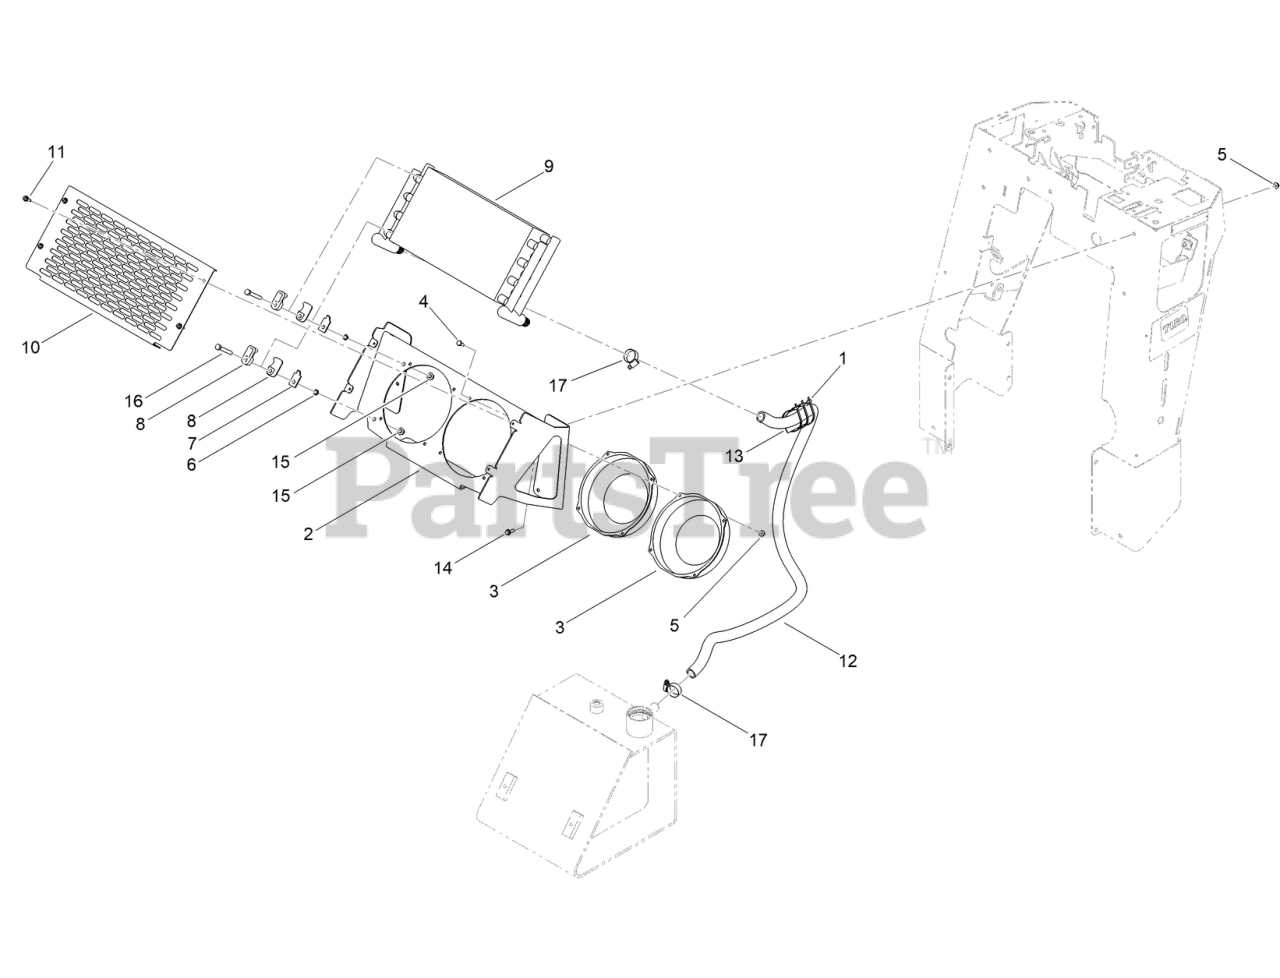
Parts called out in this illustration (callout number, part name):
1	TIE-CABLE
2	MOUNT-COOLER
4	SCREW-HH
5	NUT-HF
7	PLATE-SUPPORT, CLAMP
9	COOLER-OIL
10	COVER-COOLER
11	SCREW-HWH
12	HOSE-RETURN
13	PROTECTOR-HOSE
14	SCREW-HHF
15	NUT-HF, NI
16	SCREW-HH
17	CLAMP-HOSE
